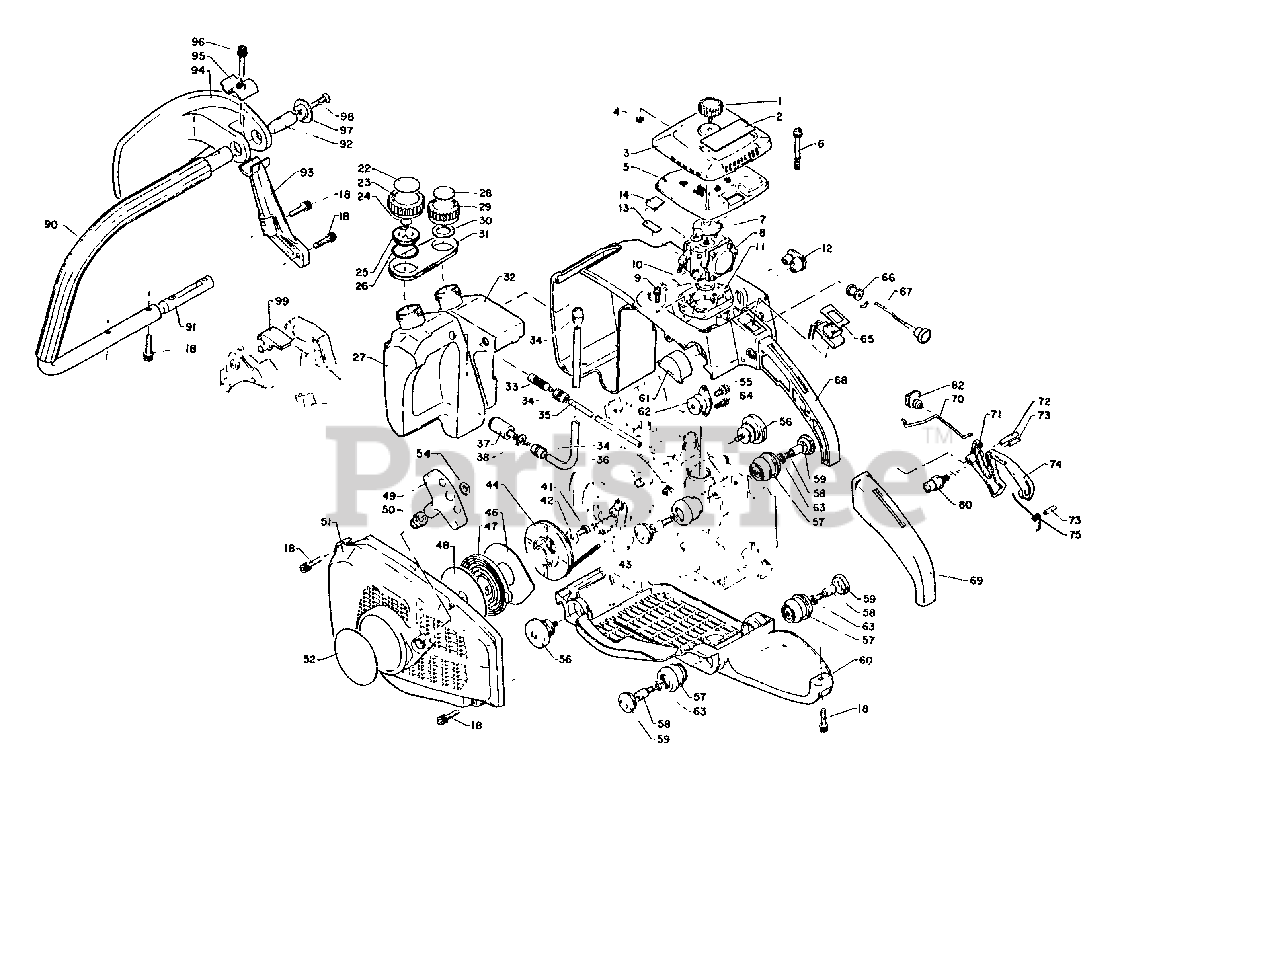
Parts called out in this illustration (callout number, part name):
1	THUMBSCREW
2	LABEL - CAUTION
3	COVER, AIR FILTER
4	RING, RETAINING - 3
5	FILTER, AIR
6	SCREW - 5X40
7	BRACKET, AIR CLEANER
8	CARBURETOR
9	SCREW - 4X12
10	SEAL
11	ADAPTOR
12	GROMMET
13	LABEL - OIL
18	SCREW - 5X20
22	LABEL - FUEL MIX
23	CAP
25	HOLDER, VENT
26	O-RING - 22
27	TANK, FUEL
28	LABEL - OIL
29	CAP, OIL TANK
30	GASKET, CAP
31	CONNECTOR
32	TANK, OIL
33	FILTER, OIL
35	OIL PIPE KIT
36	FUEL PIPE KIT
37	FILTER, FUEL
38	WASHER - 6
41	SCREW - 5X10
42	WASHER - 5
43	ROPE, STARTER
44	REEL, ROPE
46	PLATE, STARTER
47	SPRING, REWIND
48	PLATE, STARTER
49	GRIP, STARTER
50	GUIDE, ROPE
51	CASE, STARTER
52	LABEL - ECHO
54	RING, RETAINING
55	SCREW - 5X10
56	CUSHION
58	SCREW
59	CAP, CUSHION
60	SUPPORT
61	COVER, CUSHION
63	LOCKWASHER - 5
64	SCREW - 4X10
65	IGNITION SWITCH ASSY
67	ROD, CHOKE
68	HANDLE - REAR
69	GRIP, HANDLE - REAR
70	ROD, THROTTLE
71	TRIGGER, THROTTLE
72	PIN - SPRING -- 5X25
73	PIN - SPRING -- 4X13
74	LOCKOUT, THROTTLE
75	SPRING, LOCKOUT LEVER
80	LATCH, THROTTLE
90	HANDLE - FRONT
91	Insert, front handle (L)
93	BRACKET, HANDLE - UPPER
94	GUARD
95	STOPPER
96	SCREW - 5X30
97	RETAINER, GUARD
98	SCREW - 5X20
99	COVER
